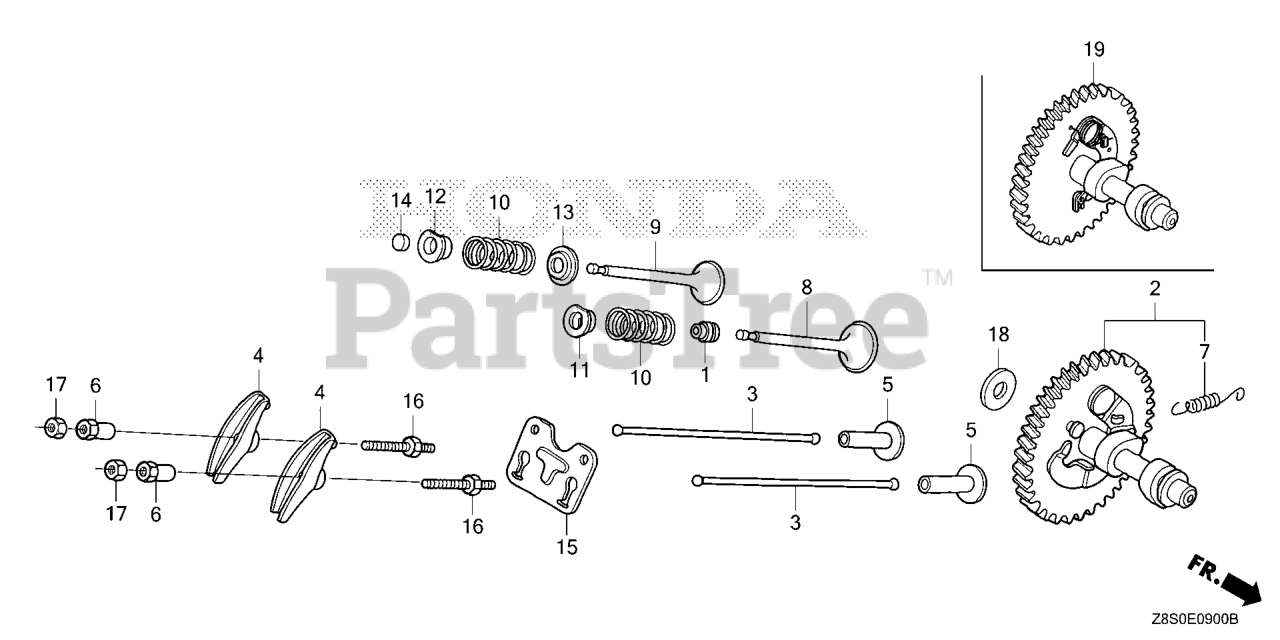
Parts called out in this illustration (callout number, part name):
1	SEAL, VALVE STEM
4	ARM, VALVE ROCKER
5	LIFTER, VALVE
6	PIVOT, ROCKER ARM
8	VALVE, IN.
9	VALVE, EX.
10	SPRING, VALVE
11	RETAINER, IN. VALVE SPRING (EXHAUST SIDE)
12	RETAINER, IN. VALVE SPRING (EXHAUST SIDE)
13	SEAT, VALVE SPRING
15	GUIDE, PUSH ROD
16	BOLT, PIVOT (8MM)
17	NUT, PIVOT ADJ.
19	CAMSHAFT COMP (STD)
